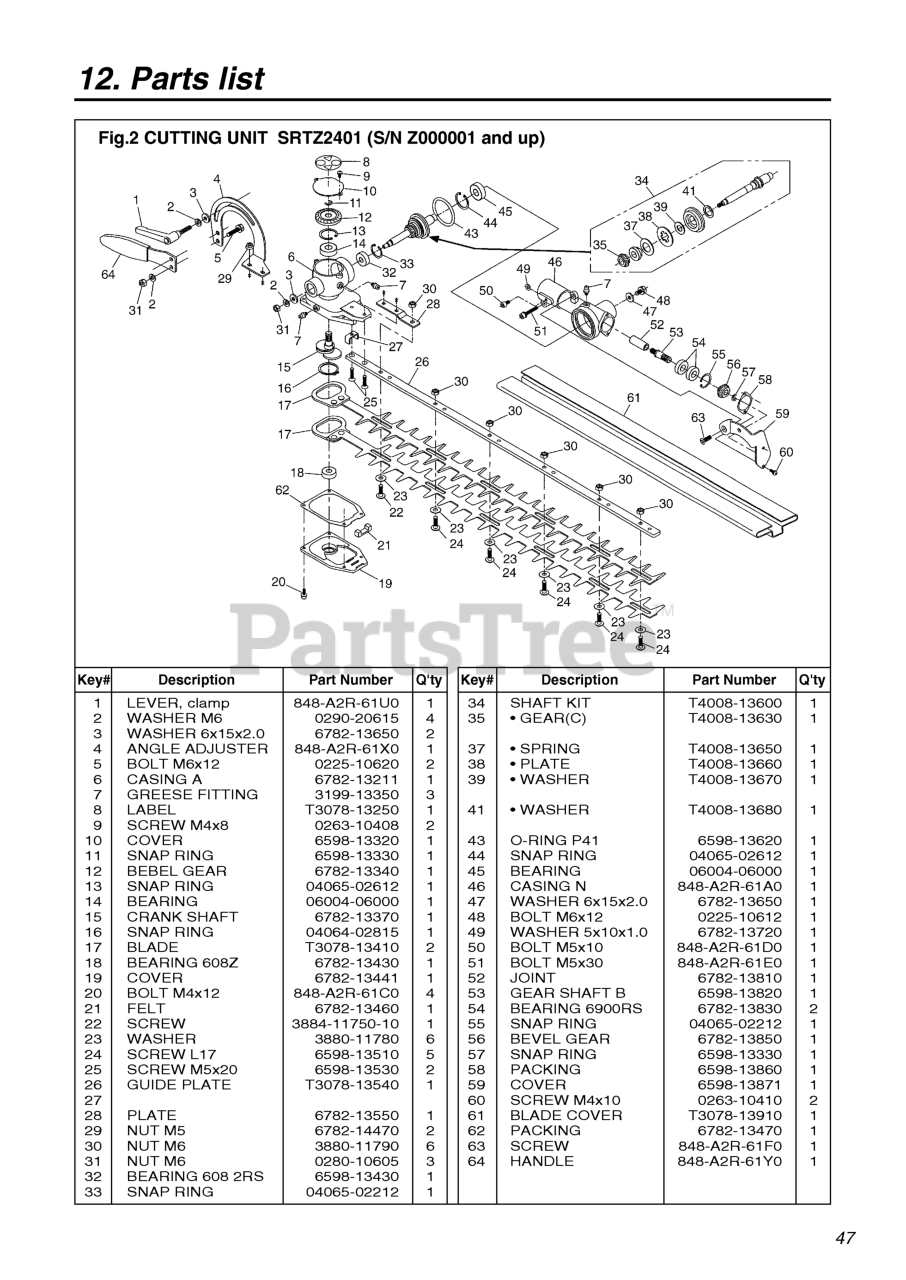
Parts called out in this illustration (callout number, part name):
1	LEVER, CLAMP
2	WASHER, M6 X 15
3	WASHER, 6X15X2.0
4	ANGLE ADJUSTER
5	BOLT
6	CASING A
7	FITTING, GREASE
8	LABEL
9	SCREW, M4 X 8
11	RING, SNAP
12	GEAR, BEVEL
13	RING, SNAP, M26 X 1.2
14	BEARING
15	CRANKSHAFT
16	RING, SNAP, M28 X 1.5
17	BLADE, SRT, 24
18	BEARING
19	COVER
20	BOLT
21	FELT
22	SCREW (RPLS 3884-11750)
23	WASHER
24	SCREW
25	SCREW, M5 X 20
26	PLATE, GUIDE
28	PLATE (RPLS 6780- )
29	NUT, M5
30	NUT, M6
31	NUT, M6 X 5
32	BEARING
33	RING, SNAP, M22 x 1.2
35	GEAR (C)
37	WASHER, SPRING
38	PLATE
39	WASHER
41	WASHER
43	O-RING
44	RING, SNAP, M26 X 1.2
45	BEARING
46	CASING N
47	WASHER, 6X15X2.0
49	WASHER
50	BOLT
51	BOLT
52	JOINT (REPLACES T3078-13810)
53	SHAFT, GEAR
54	BEARING
55	RING, SNAP, M22 x 1.2
56	GEAR, BEVEL
57	RING, SNAP
58	PACKING
60	SCREW, M4 X 10
61	COVER, BLADE
62	GASKET
63	SCREW
64	HANDLE
